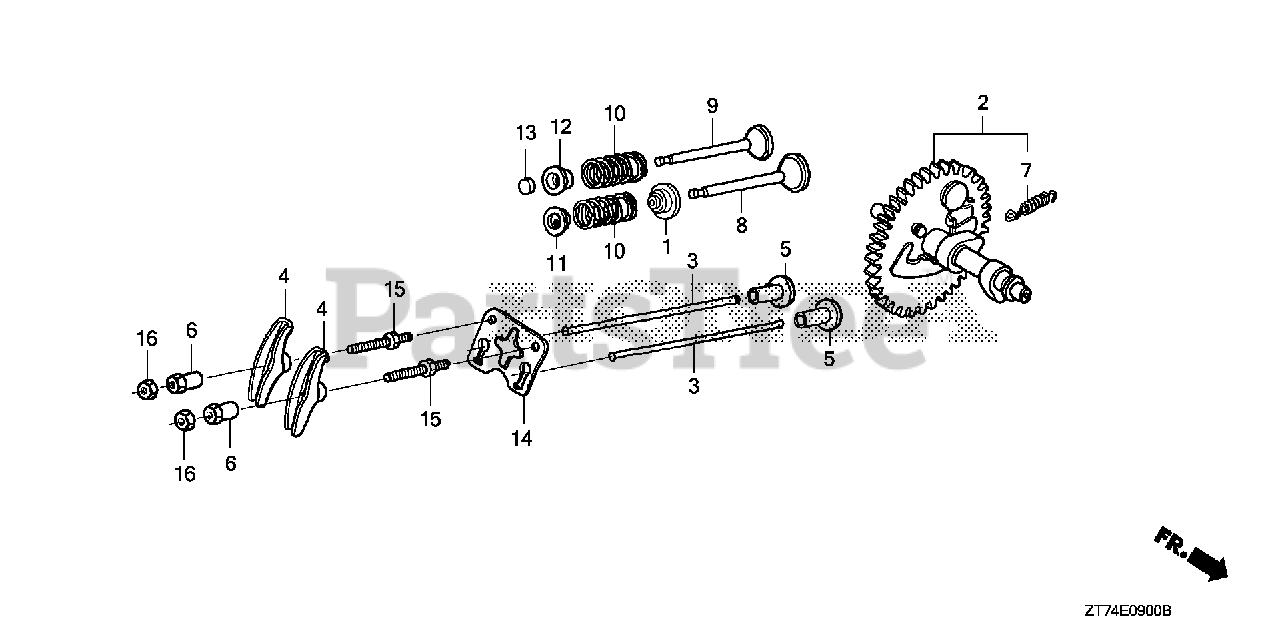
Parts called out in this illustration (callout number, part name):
1	SEAL, VALVE STEM
2	CAMSHAFT ASSY.
4	ARM, VALVE ROCKER
5	LIFTER, VALVE
6	PIVOT, ROCKER ARM
7	SPRING, WEIGHT RETURN
8	VALVE, IN.
9	VALVE, EX.
10	SPRING, VALVE
11	RETAINER, IN. VALVE SPRING
11	RETAINER, VALVE SPRING
12	RETAINER, EX. VALVE SPRING
13	ROTATOR, VALVE
14	PLATE, PUSH ROD GUIDE
15	BOLT, PIVOT (8MM)
16	NUT, PIVOT ADJUSTING
